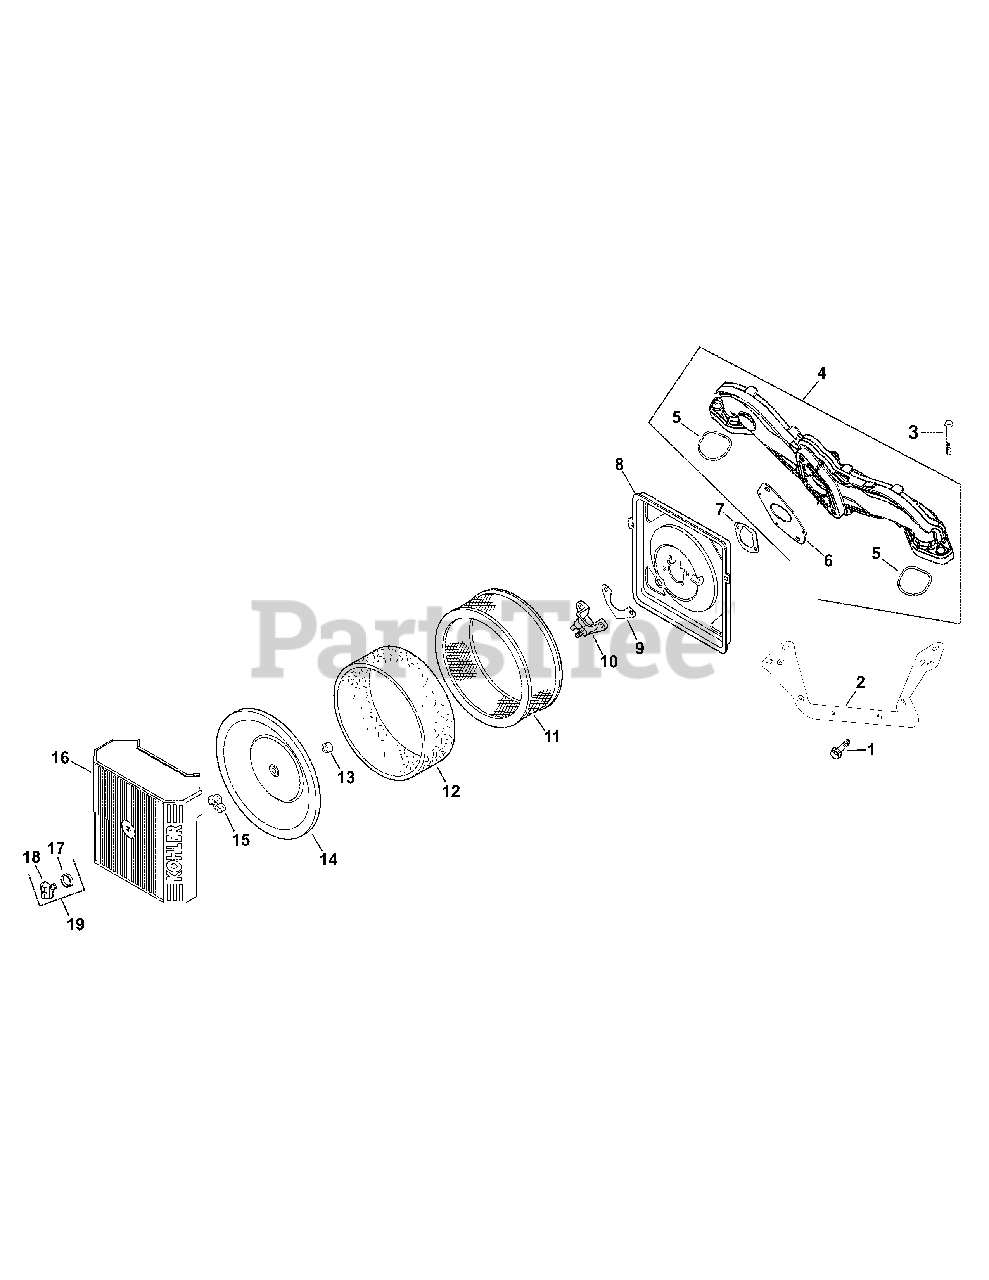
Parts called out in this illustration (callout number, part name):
1	Screw, Flg Thd Frm M5 x .8 x 10
2	Bracket, Air Cleaner Base
3	Screw, Flg M6x1.0x40
4	Manifold, Intake
5	O-Ring, Intake Port
6	Gasket, Carburetor
7	Gasket, Air Cleaner Base
8	Base, Air Cleaner
9	Gasket, Fuel Spitback Cup
10	Cup, Fuel Spitback W/O Nipple
11	Elements, Air Filter & Pre Cleaner
12	Pre-Cleaner
13	Seal, Breather
14	Cover, Inner Air Cleaner
15	Nut, Wing
16	Cover, Air Cleaner
19	Kit, Knob W/ Seal
